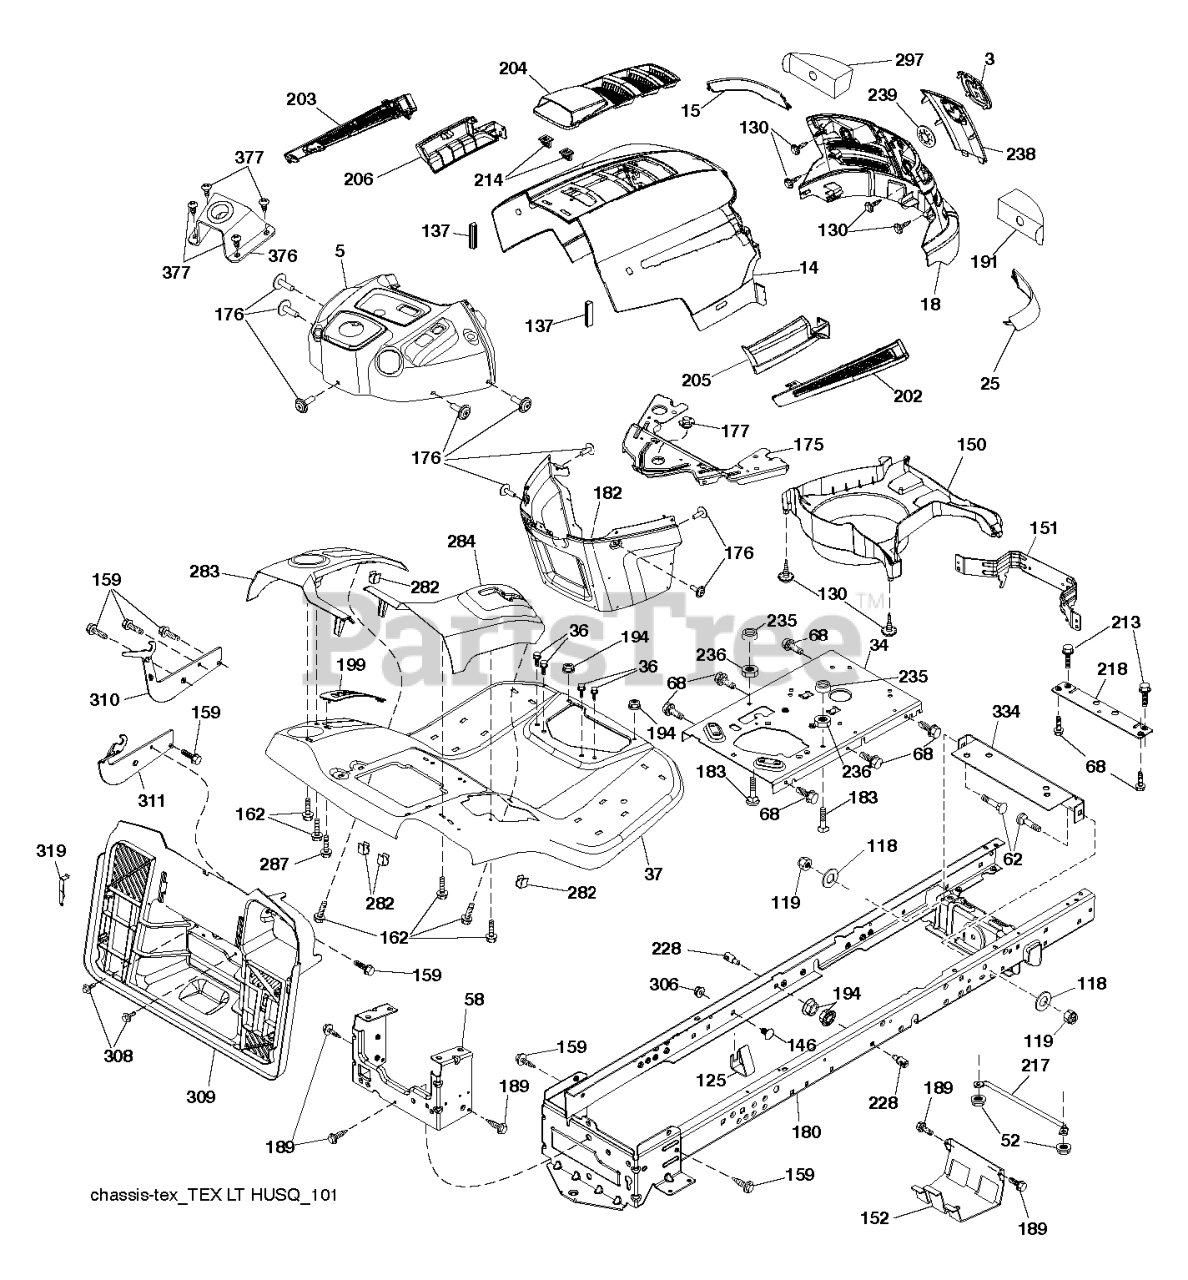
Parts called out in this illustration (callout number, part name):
3	LOGO.HUSQ.GT.LT.CROWN.H
5	SUBASM.DASH.UPPER.W/BUMPER
14	HOOD.HUSQVARNA.LT.ORANGE
15	LENS.HUSQVARNA LT.RH
18	ASM.GRILLE HUSQVARNA.LT.498
25	LENS.HUSQVARNA LT.RH
36	SCREW 5/16"
37	FENDER.TEX.SRD.CRD.BASE
58	DRAWBAR UPPER 2PC SMALL FENDER
118	WASHER PLAIN WASHER 3/8 X 0.08
125	CLIP.FUEL.LINE
137	BUMPER DASH
146	BOLT.RDHD.SHT.SQNK.3/8-16X5/8
151	BRACKET PIVOT
152	SHIELD.BROWNING.W/TEX
159	SCREW, 3/8-16X3/4
175	CROSSMEMBER
176	SCREW.#10-24X5/8.RN.QU
177	BUSHING STEERING
180	CHASSIS.WLDMNT.14GA.2PC.18".TI
182	DASH.LOWER.PREDATOR LT
189	SCREW
191	INSERT.REFLECTIVE.RH.
199	PLATE DECK LIFT
202	VENT.SIDE.HUSQVARNA.LT.RT
203	VENT.SIDE.HUSQVARNA.LT.LFT
204	SUBASM.TOP.VENT.HUSQ.LT
205	SKIRT.SIDE.HUSQVARNA.LT.RT
206	SKIRT.SIDE.HUSQVARNA.LT.LEFT
213	SCREW HEXAGON HEAD SCREW 5/16-
214	CLIP.RETAINER.TINNER.
217	ROD.PIVOT.HOOD
218	X-PIECE.HOOD.STOP.NON/
228	STUD.W/"D"ANTI-ROTATION
236	NUT.CENTERLOCK.5/16-
238	TRIM.HUSQ LT.668
282	CLIP.RETAINER.CONSOLE.LT.HUSQ
283	CONSL.DECKLIFT.LH.SRD.TEX.CRD
284	CONSL.SHFT.PEDAL.RH.SRD.TEXCRD
287	SCREW 1/4X20
297	INSERT REFLECTIVE
306	NUT LOCK FLG 3/8-16 UNC
308	BOLT.5/16-18UNCX3/4 W/SEMS.BLK
309	BACKPLATE.BAGGER.V2.SRD
310	BRACKET BRACKET.LH REAR BAG HA
311	BRACKET BRACKET.RH REAR BAG HA
319	BRACKET.ACTUATOR.BAGGER.SRD
334	BRACKET.ENGINE
376	MOUNT.ASM.HUSLT.UPPER.STRNG
377	SCREW 10 X 1/2 ZN PL PHIL PAN
